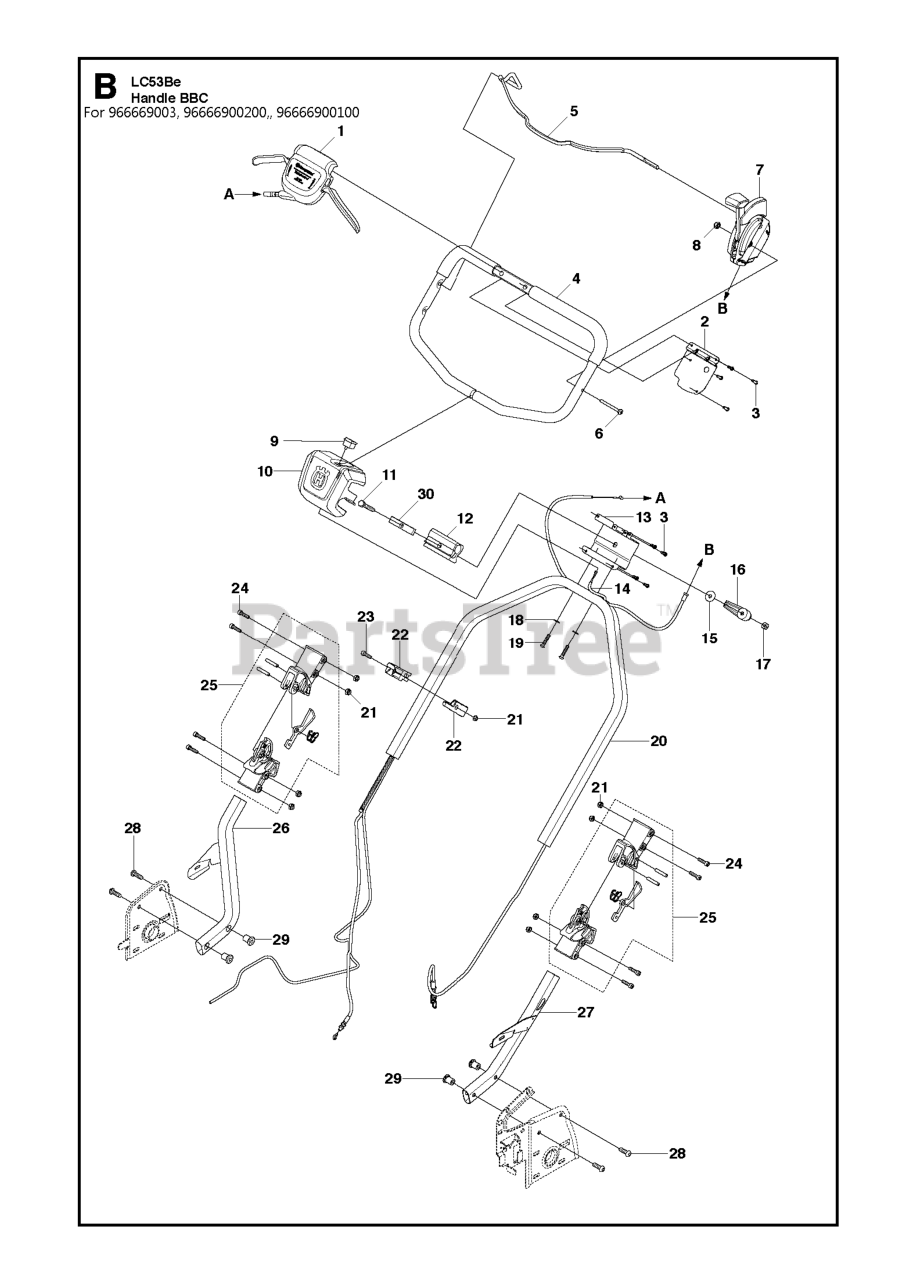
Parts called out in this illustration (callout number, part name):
15	WASHER - 25X8.5X2.3
23	SCREW MC6S 6X20
24	REPL BY 725 53 74-55
30	BRACKET
